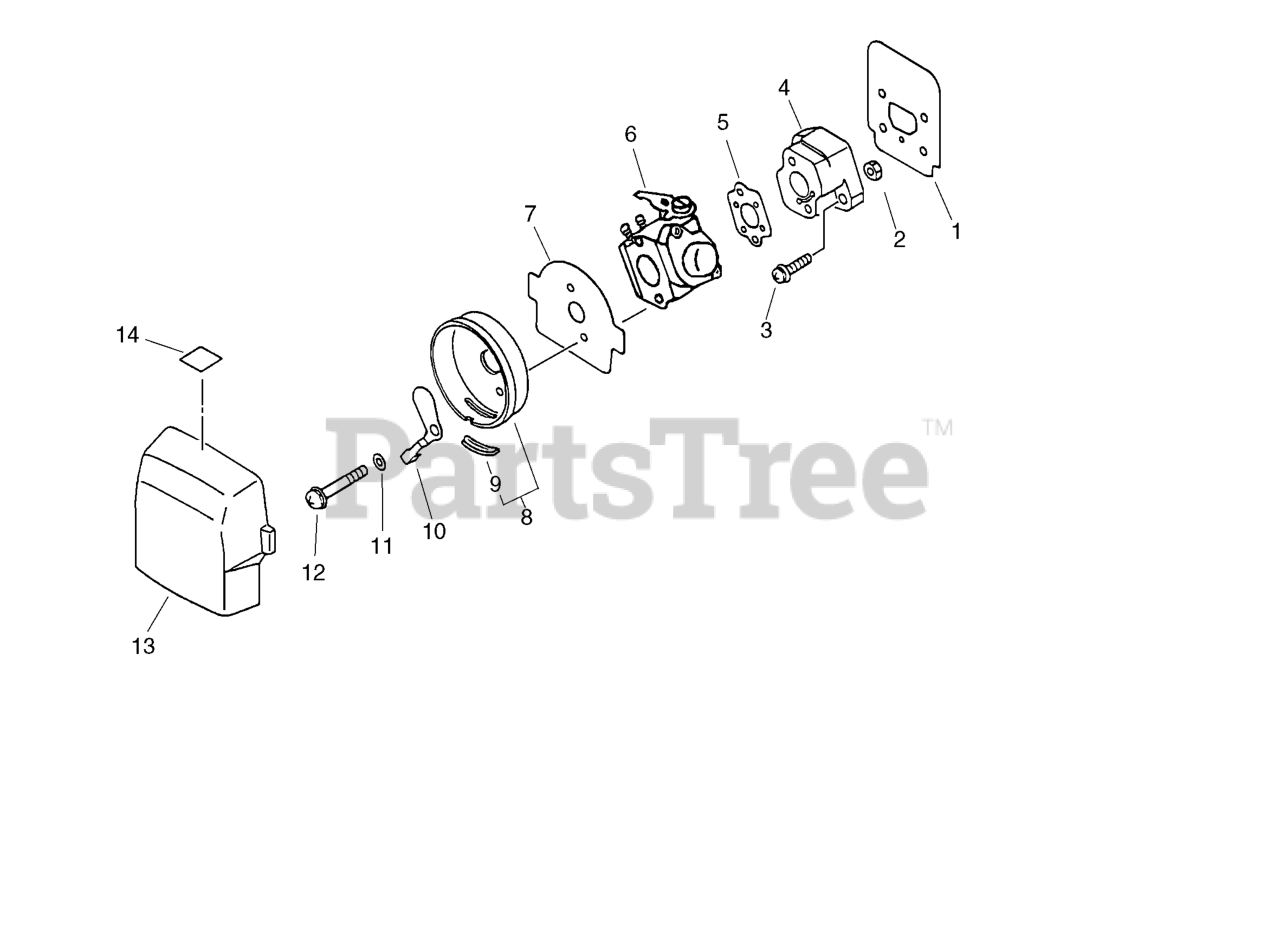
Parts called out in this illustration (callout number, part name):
1	HEAT SHIELD, INTAKE
3	SCREW 5×20
4	INSULATOR, INTAKE
5	GASKET, INTAKE
6	CARBURETOR
7	PLATE, AIR FILTER
8	CASE, AIR FILTER
9	BUSHING
10	SHUTTER, CHOKE
11	WASHER 5.2×8×0.8T
12	SCREW 5×57
13	FILTER, AIR
14	LABEL - ADJUSTING
